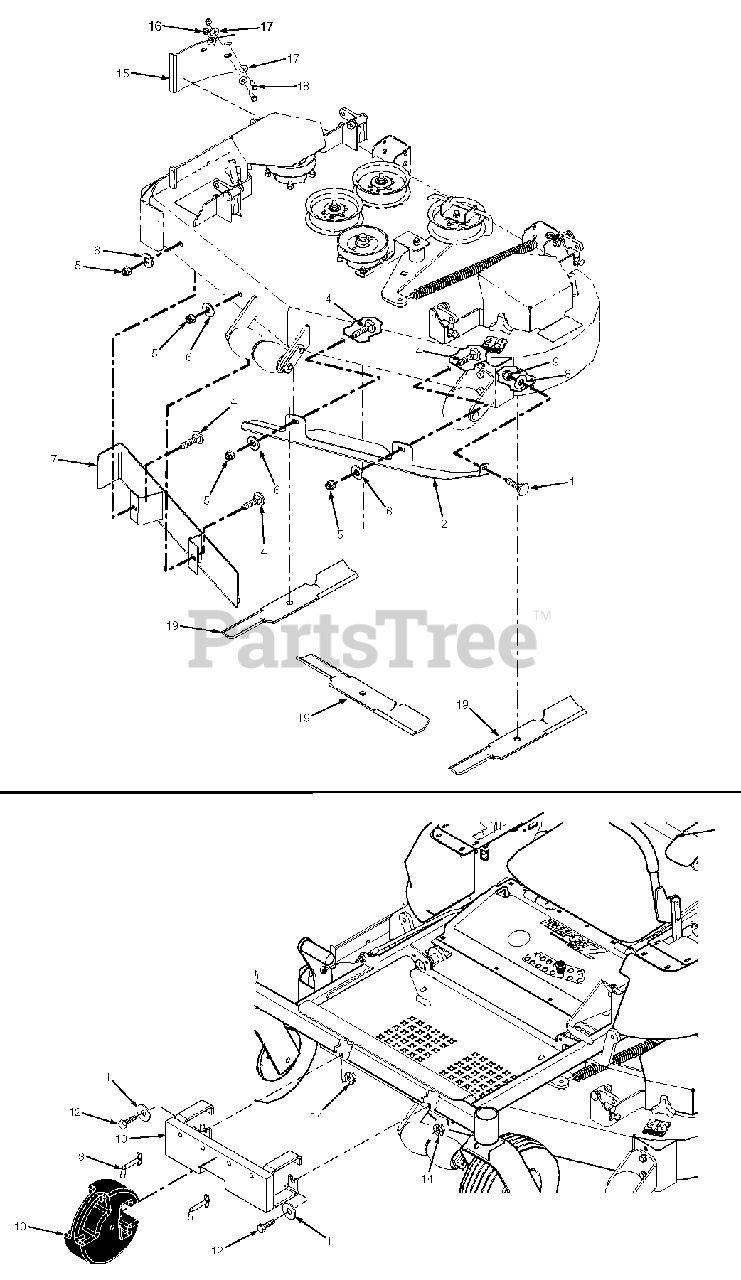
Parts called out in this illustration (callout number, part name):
1	Bolt, Carriage 5/16-18 x 3/4"
2	Baffle, LH - 52" Deck
2	Baffle, LH - 61" Deck
3	Pin, Weight Retention
4	Bolt, Carriage 3/8-16 x 1"
5	Nut, Elastic Stop 3/8-16
6	Flatwasher, 3/8-.438 x 1.00 x .083
7	Baffle, Weldment, RH - 52" Deck
7	Baffle, Weldment, RH - 61" Deck
8	Flatwasher, 5/16-.344 x .688 x .065
9	Nut, Center Lock 5/16-18
10	Weight Assembly
11	Flatwasher, 1/2-.562 x 1.375 x .109
12	Bolt, Hex Head 1/2-13 x 1-1/4"
13	Support Weldment, Weight Mounting
14	Nut, Serrated Flange 1/2-13
15	Filler Plate - 52
15	Filler Plate - 61
16	Nut, Center Lock 5/16-18
17	Flatwasher, 5/16-.375 x .875 x .083
18	Bolt, Hex Head 5/16-18 x 1"
19	Cutter Blade, High Lift (52" Deck)
19	Cutter Blade, High Lift (61" Deck)
